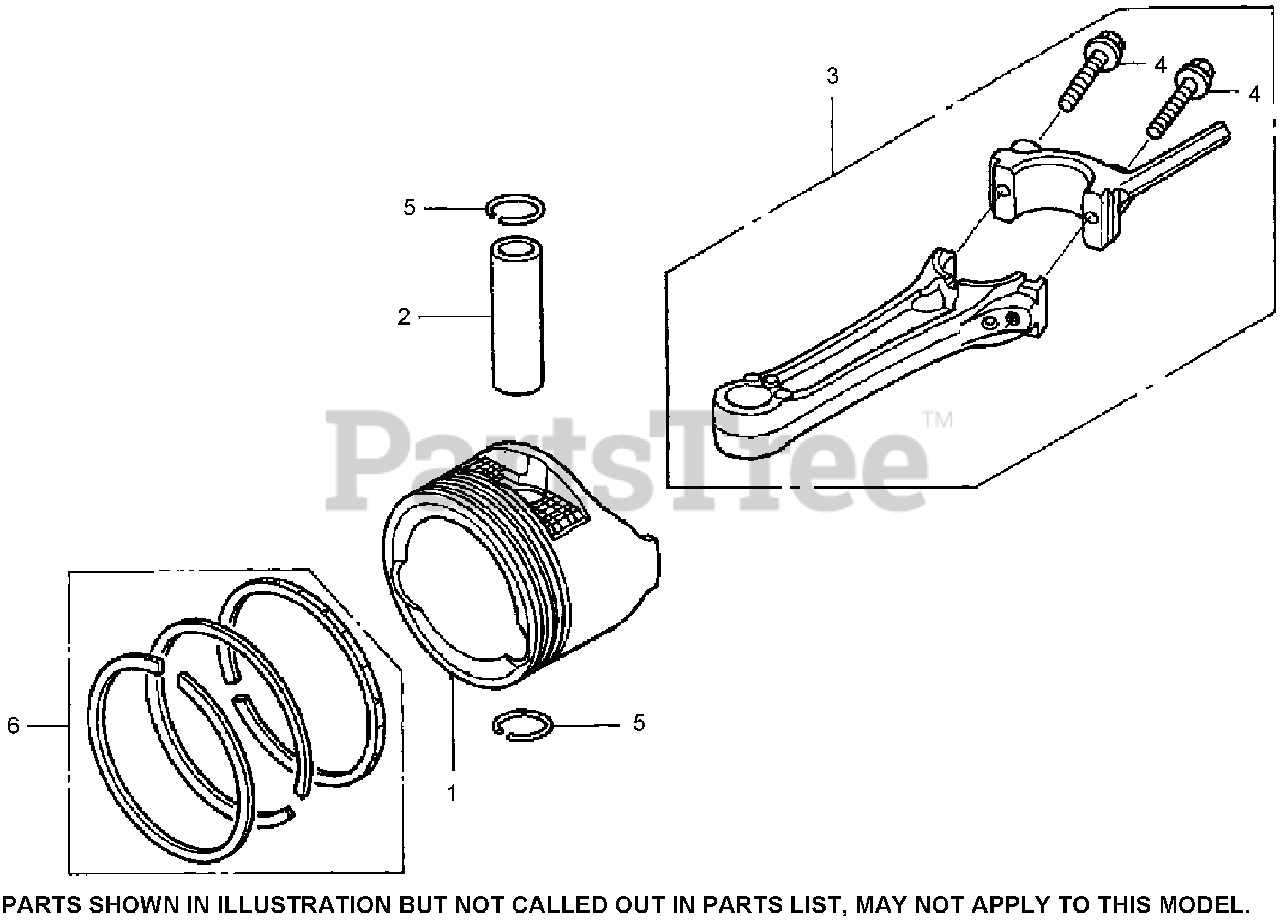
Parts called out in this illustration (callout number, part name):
1	PISTON
2	PIN, PISTON
3	ROD ASM., CONNECTING
4	BOLT-CONNECTING ROD
5	CLIP, PISTON PIN (13MM)
6	RING SET, PISTON (RIKEN)
